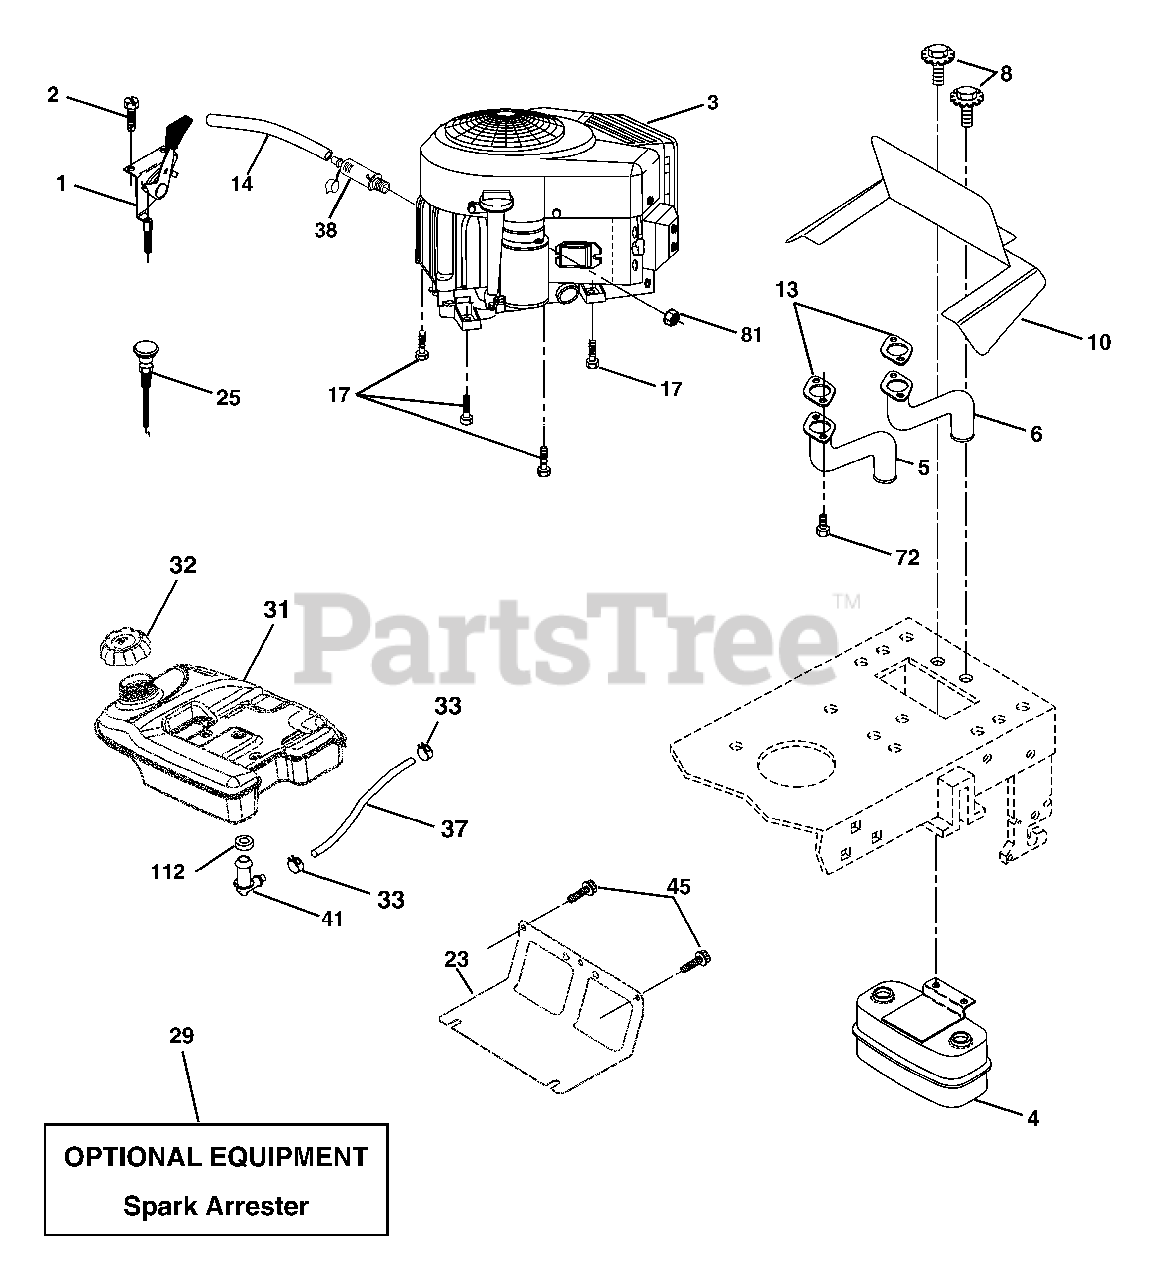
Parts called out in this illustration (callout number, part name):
1	Control Th/ch Flag
2	Screw Hex Thd Cut 1/4-20 x 1/2
5	Exhaust Tube LH
6	Exhaust Tube RH
8	Bolt 5/16-18 unc x 3/4
10	Shield Heat Muffler
14	Tube Drain Oil Easy
17	Screw 3/8-16 x 1-1/2
23	Shield Browning/Debris Guard
25	Control Choke
26	Nut Keps 3/8-24 unf
29	Kit Spark Arrestor (Flat Scrn)
32	Cap Asm Fuel
33	Clamp Hose Black
37	Line Fuel
38	Plug Drain Oil Easy
41	Stem Tank Fuel
45	Screw Hex Wsh Thdr 3/8-16 x 3/4
72	Screw Socket Head 5/16-18 x 1
81	Nut Keps Hex 1/4-20 Starter Nut
112	Bushing
